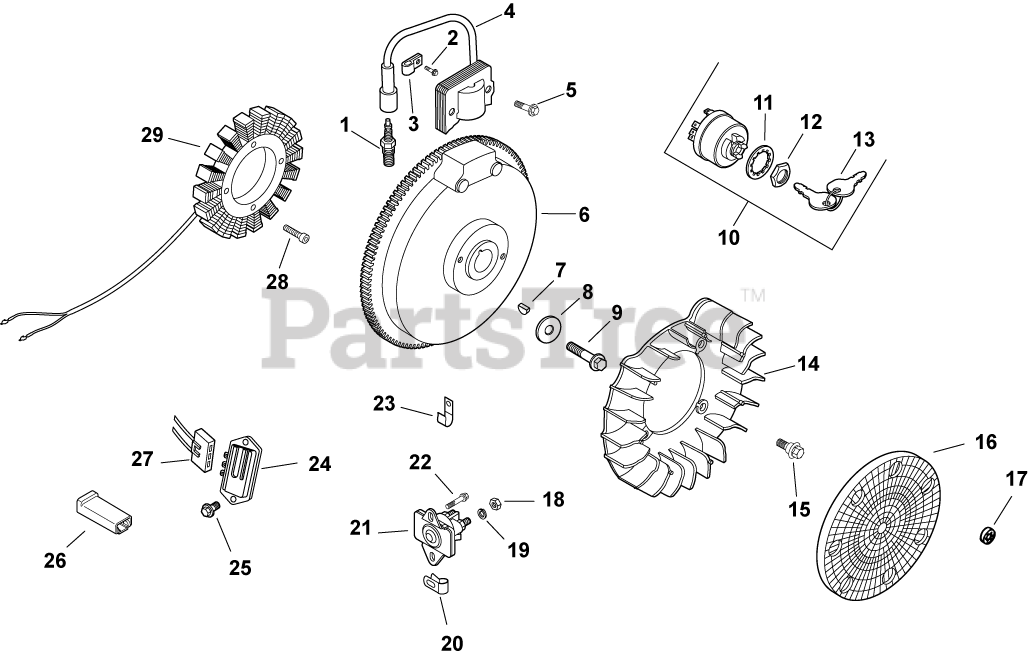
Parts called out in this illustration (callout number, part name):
1	PLUG, SPARK (PRO SERIES)
2	SCREW, FLG THD FRM M5X.8X10
4	MODULE, IGNITION
5	SCREW, FLG THD FRM M5X.8X20-(#25086399S)
6	FLYWHEEL - USE 12 025 16-S
7	KEY, 3/16" X 5/8"
8	WASHER, FLAT 13/32"
9	SCREW, FLG M10X1.5X45 - (#25086361S)
10	SWITCH ASSY, KEY (KM)-USE 25 099 32-S
11	WASHER, INTERNAL TOOTH
12	NUT, KEY SWITCH
13	KEY, SET -USE 48 340 01-S
15	BOLT, SHOULDER
16	SCREEN, GRASS
18	NUT, JAM 1/4-20 GRADE 2
19	WASHER, INT TOOTH LOCK 1/4"
20	CLIP, TUBE & WIRING (KM)
21	SOLENOID - WATERPROOF (KM)-USE 25 435 08
22	SCREW,FLG THD FRM M6X1.0X16-(#25086397S)
23	CLIP, CABLE
24	REG/RECT-15 AMP (KM)-USE 41 403 10-S
25	SCREW, FLG M6X1.0X16
26	CONNECTOR (1 CONTACT)
27	CONNECTOR, BODY (KM)-USE 25 155 41-S
28	SCREW, M5X0.8X25 - (#25086402S)
29	KIT, 15 / 20 AMP STATOR
1251809-S	LEAD, STARTER SOLENOID - DISCONTINUED
